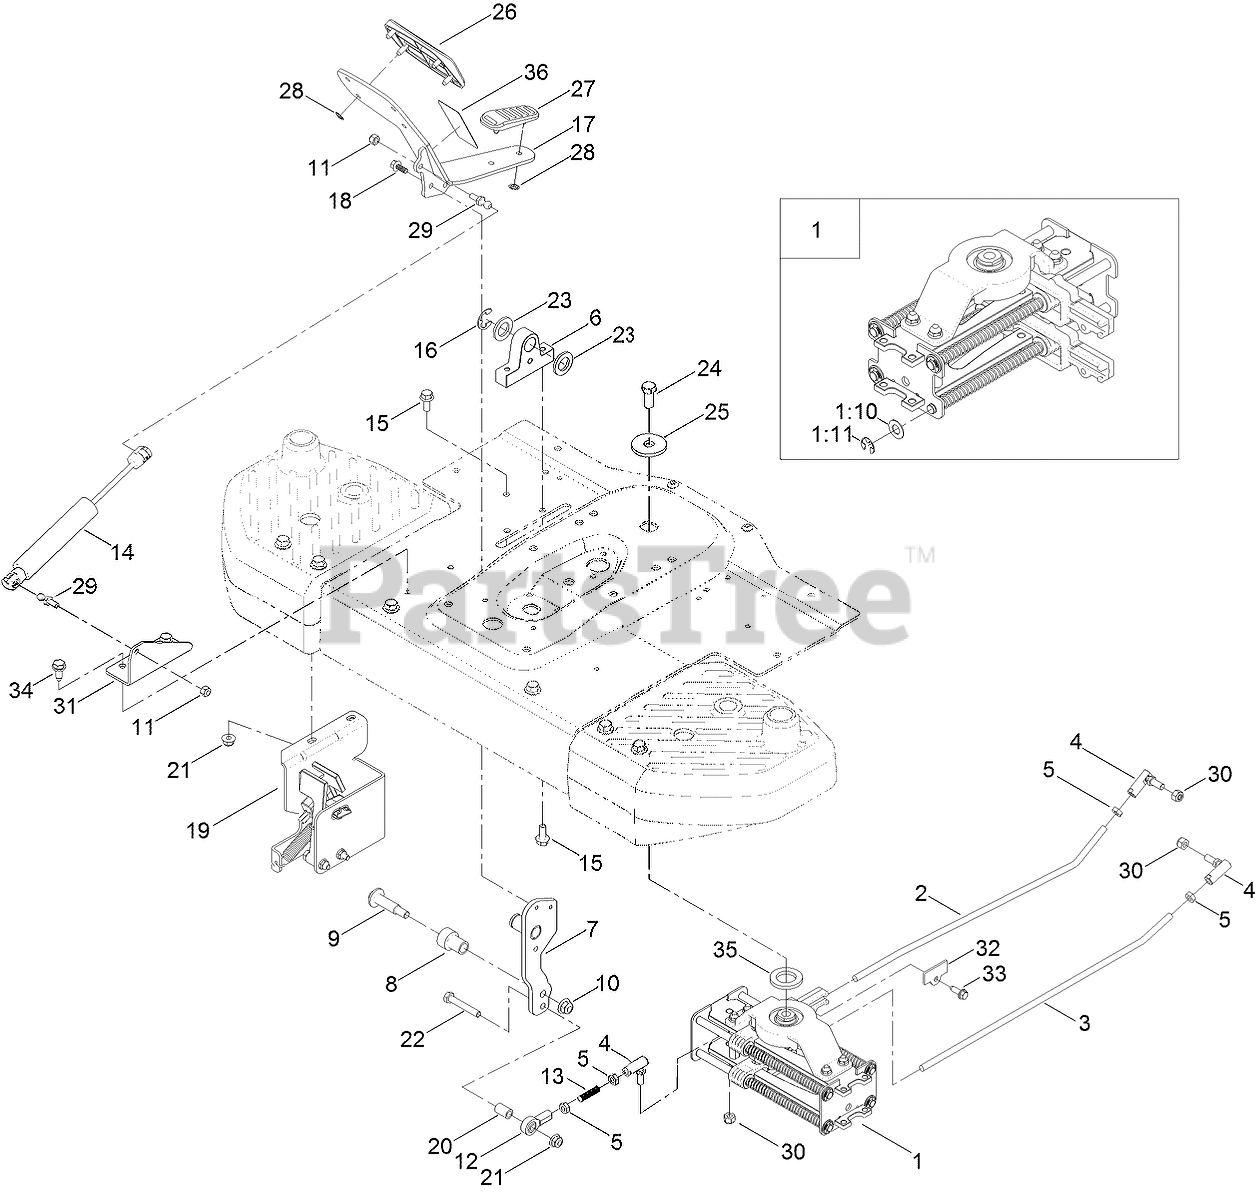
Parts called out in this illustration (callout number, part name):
1	SPEED CONTROL ASM
1:10	WASHER-THRUST
1:11	E-RING
2	ROD-HYDRO, RH
3	ROD-HYDRO, LH
4	BALLJOINT-RH (W/GROMMET)
5	NUT-JAM
6	MOUNT-PEDAL PIVOT
7	PIVOT LEVER ASM
8	ROLLER
9	BOLT-WHEEL
10	NUT-HF, NI
11	NUT-LOCK, NI
12	BALLJOINT-RH
13	ROD-THREADED
14	DAMPER-NON CAVITATING
15	SCREW-HHF
16	E-RING
17	PEDAL-TRACTION
18	SCREW-HHF
19	NEUTRAL RETURN ASM
20	SPACER
21	NUT-HF, NI
22	SCREW-HH
23	WASHER
24	SCREW-HH
25	WASHER-THRUST
26	PAD-TOE, HYDRO PEDAL
27	PAD-HEEL, HYDRO PEDAL
28	NUT-PUSH
29	BALL STUD
30	NUT-LOCK
31	BRACKET-DAMPER
32	COVER-END ROD
33	SCREW-HWH, THREAD ROLL
34	SCREW-HWHTF
35	SPACER-BEARING
36	DECAL-RELEASE, BREAK
